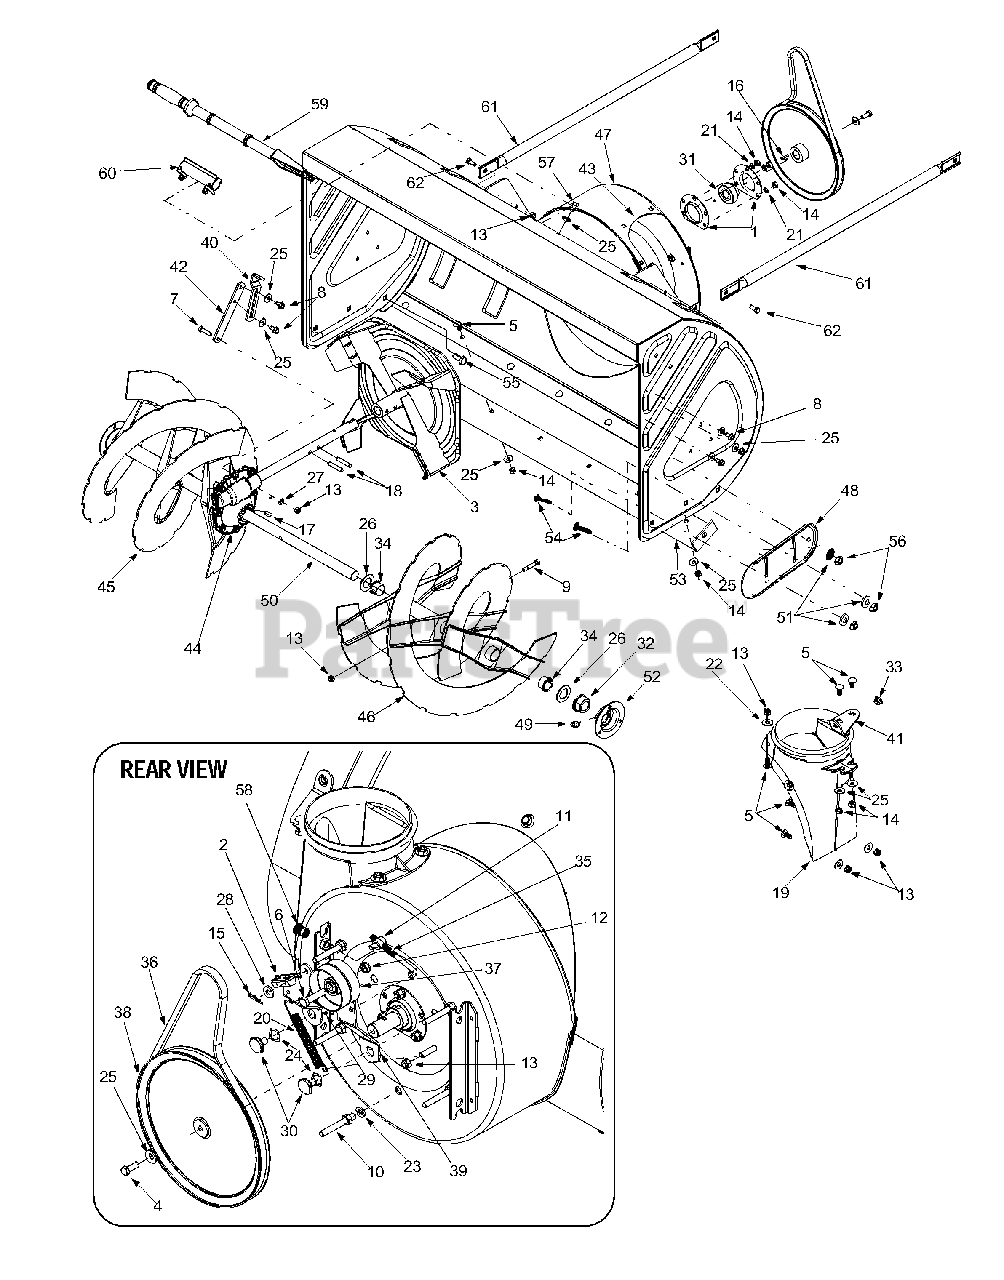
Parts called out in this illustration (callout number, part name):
1	Bearing Housing
2	Bracket Assembly, Auger Break
5	Carriage Bolt 5/16-18 x .750"
6	Hex Screw, Special 3/8-24 x 1.5"
7	Hex Screw 5/16-18 x 1.25"
8	Self-Tapp. Screw 5/16-18 x .625"
9	Shear Bolt 5/16-18 x 1.75"
11	Ferrule
12	Jam Nut 3/8-24
13	Hex Lock Nut 5/16-18
14	Hex Nut 5/16-18
15	Hairpin Clip
18	Spiral Pin
19	Chute Adapter
20	Extension Spring
21	Lock Washer
22	5/16 Washer
23	Lock Washer
24	Wave Washer
25	Beleville Washer
26	Flat Washer
27	Spring Washer
28	Flat Washer
30	Shoulder Screw
31	Self-Aligning Bearing
32	Flange Bearing w/ Flats
33	Plastic Bushing
34	Flange Bushing
35	Idler Rod, Auger
36	V-Belt
37	Flat Idler
49	Lube Fitting
50	Spiral Axle
51	Bell Washer
54	Carriage Screw
55	Carriage Bolt
56	Hex Nut 3/8-16
57	Screw, 5/16-18 x .75
58	Insert Nut, 3/8-16
59	Chute Clean-out Tool
60	Mount, Chute Clean-out Tool
61	Support Tube
62	Screw, 5/16-18 x .75"
